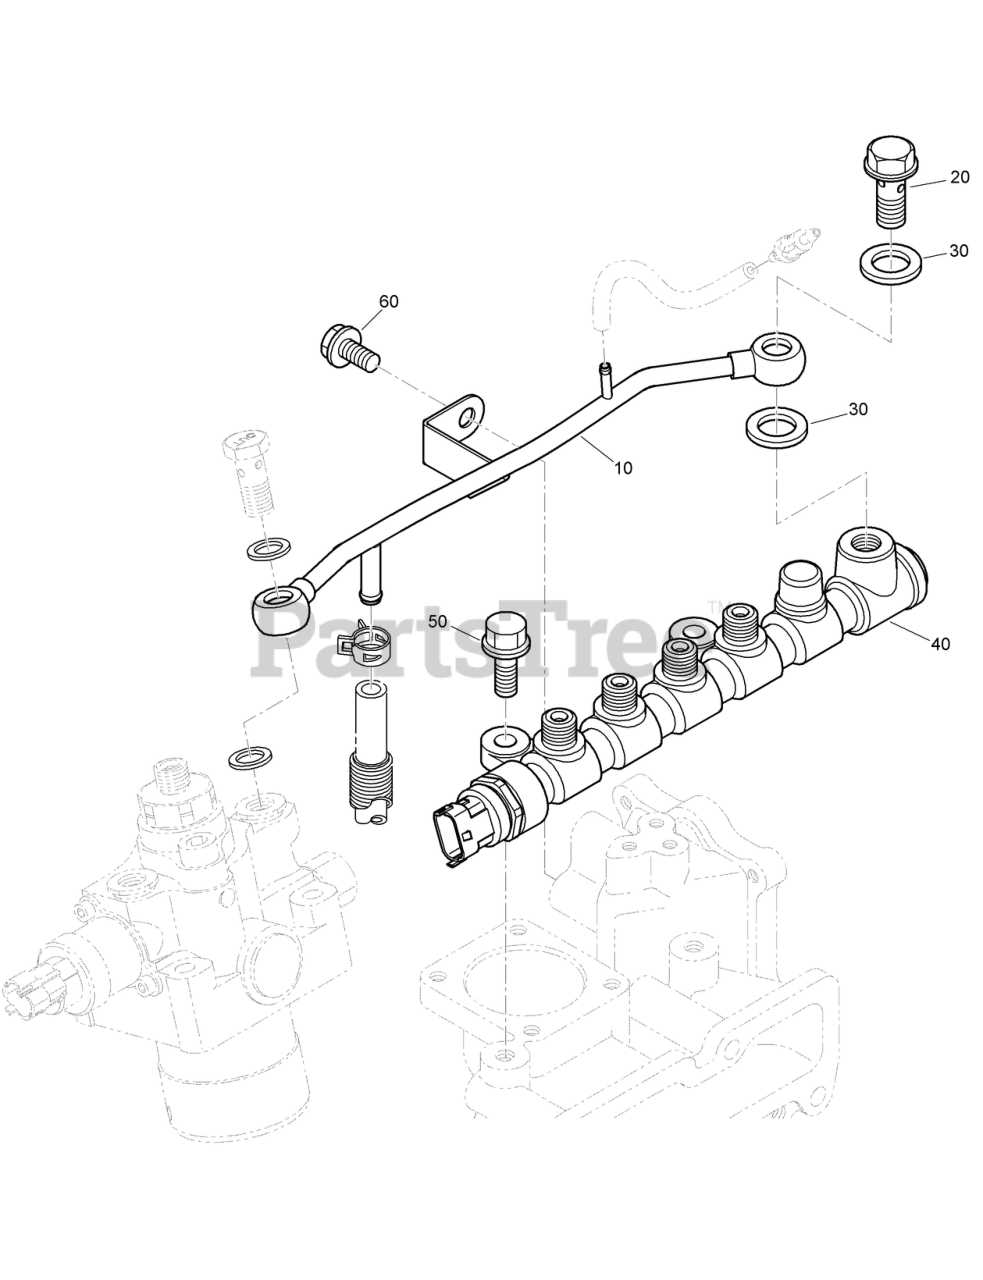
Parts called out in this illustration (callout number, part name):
10	PIPE-OVER FLOW, WATER
20	BOLT-JOINT
30	GASKET
40	RAIL ASM
50	BOLT-FLANGE
60	BOLT-FLANGE
